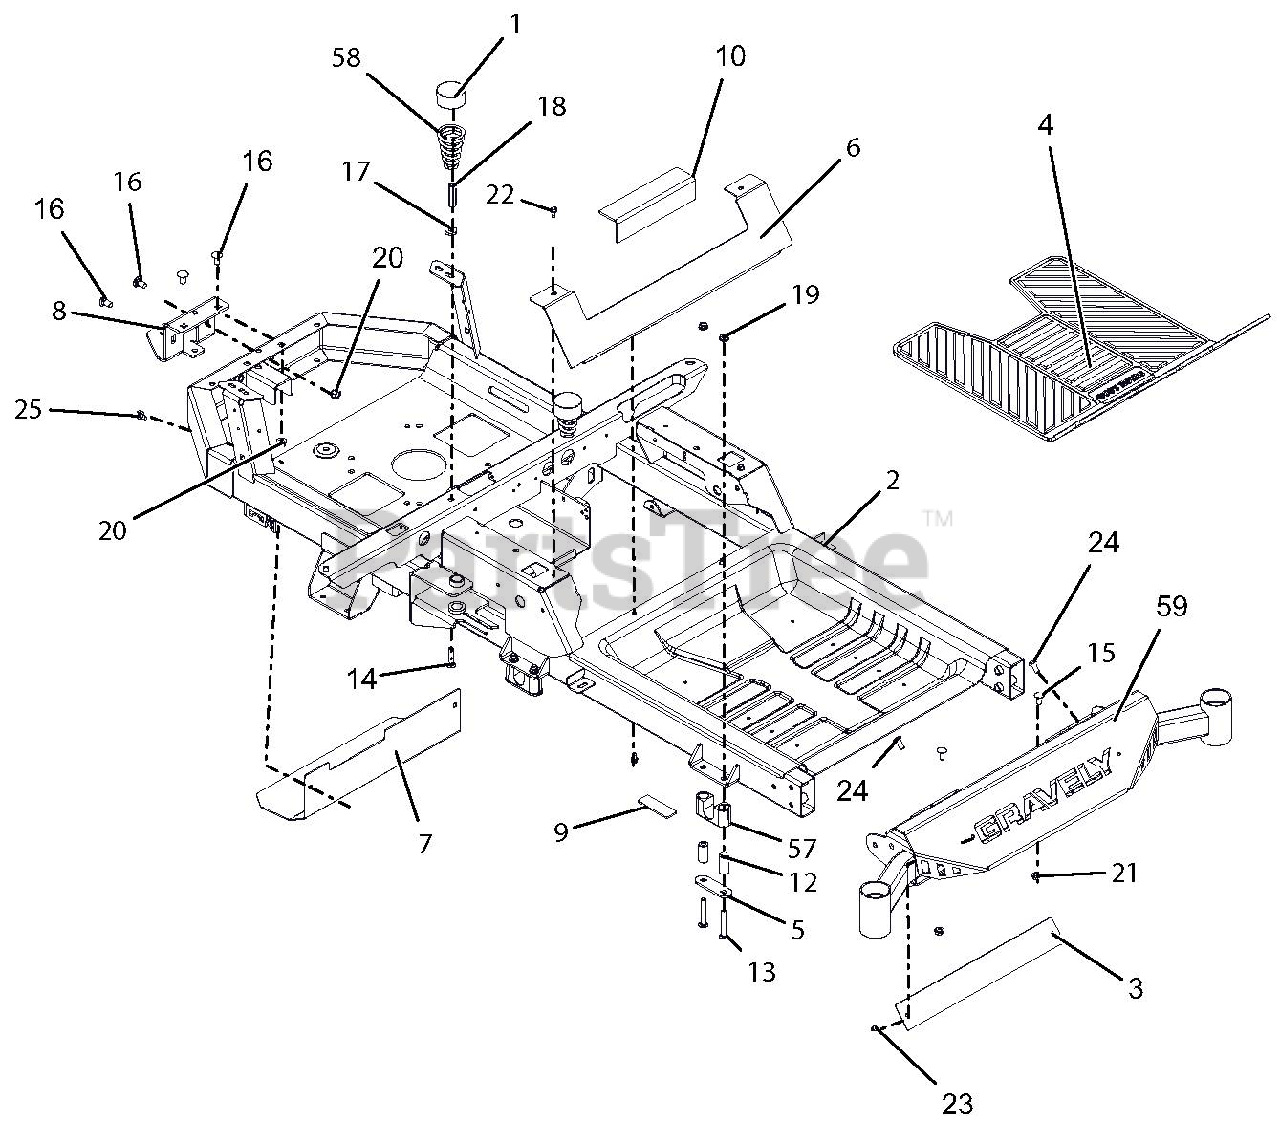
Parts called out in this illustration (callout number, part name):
2	WLDMT, FRAME IKON/ZTX
3	PLATE, BACK XL FOOT-REST
4	FLOOR MAT-RUBBER-GRAVELY
5	PLATE, BEARING SUPPORT
6	PLATE, SEAT KICK
7	HEAT, SHIELD
8	BRKT, HITCH-RED
9	PAD, RBR 1.0"X3.0" W/ADHESIVE
10	PAD, RBR -TANK
12	SPCR, SLV .323X.448X1.403
13	BLT-RDHDSQSHNK .31-18X2.25 YWZC
14	BLT-RDHDSQNK .31-18X1.50 G5 YWZC
15	BLT-RDHDSQNK .31-18X.75 G5 YWZC
16	BLT-RDHDSQNK .38-16X.75 G5 YWZC
17	WSHR-FL-STL, .328X.87X.179 YWZC
18	NUT, COUPLER 5/16-18 x 1.75
19	NUT, LK-CTR-FLG .31-18 YWZC
20	NUT, LK-TOP-FLG .38-16 YWZC
21	NUT, LK-TOP-FLG .312-18 YWZC
22	SCR-TAP .25-20X.50 HWH TR YWZ
23	RVT, POP .187x.250 AL/AL
24	SCR-TAP 10-24X.25 CRSLPH TR YZ
25	SCR-TAP .31-18X.50 HWH TR YWZ
57	BSHG, DECK LIFT PIVOT
58	SPRG, COMPRESSION
59	KIT, FOOTREST W/DECAL-ZTX
